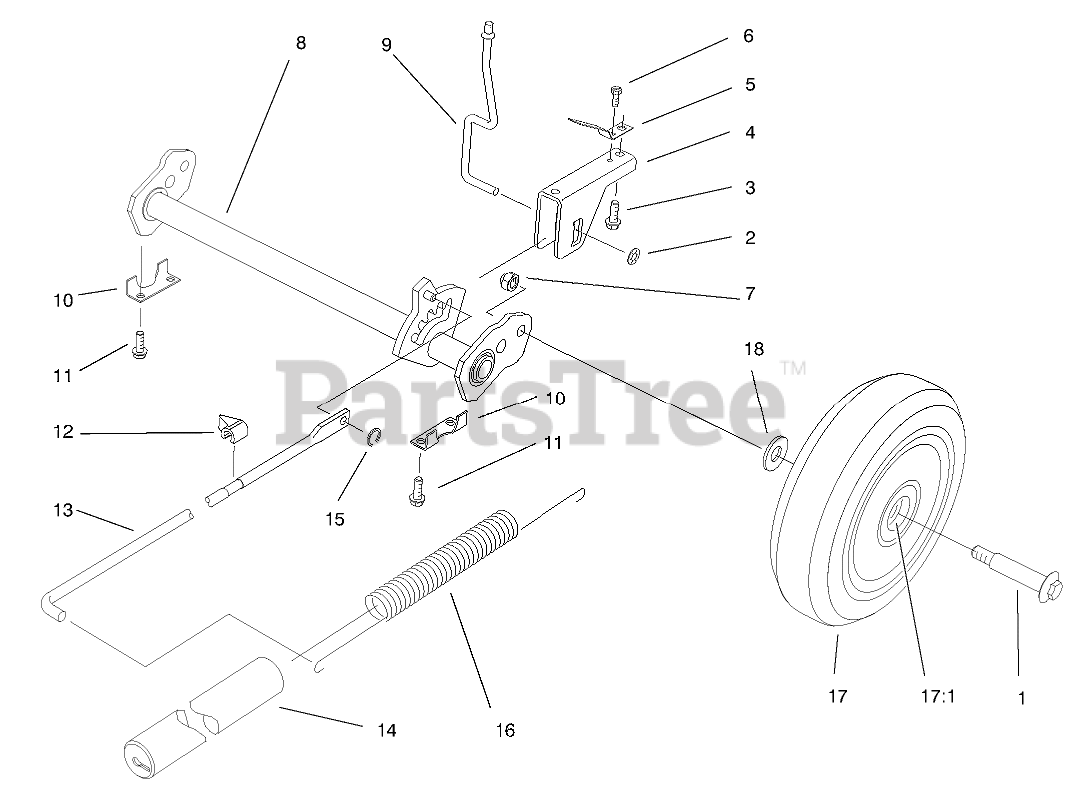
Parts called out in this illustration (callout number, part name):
1	BOLT-WHEEL
2	PUSHNUT
3	SCREW
4	SADDLE - HOC
5	SPRING - TRIGGER RET
6	SCREW 8 - 32 X 250
7	NUT-HEX
8	PIVOT ARM REAR WA
9	TRIGGER ROD
10	REAR SECURING PLATE
11	SCREW-HWH
12	INDICATOR-HEIGHT OF CUT
13	LINK ROD
14	COVER-SPRING
15	GRIP RING
16	SPRING-COUNTERBALANCE
17	Wheel-ASM
17:1	BUSHING
18	WASHER
